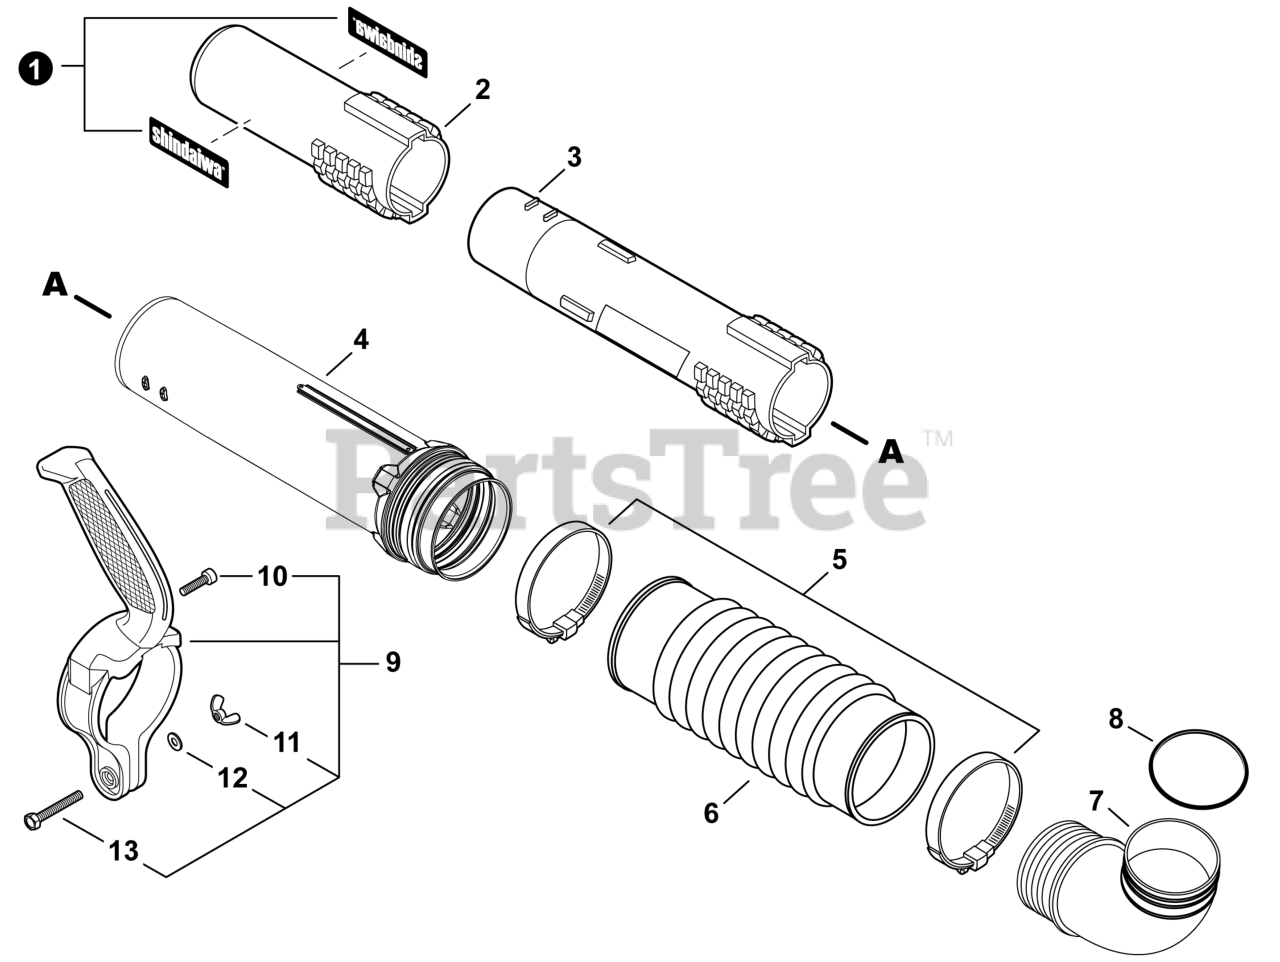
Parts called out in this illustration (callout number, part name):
1	LABEL - SHINDAIWA BLOWER TUBE
2	TUBE, BLOWER - NOZZLE
3	TUBE, BLOWER - STRAIGHT
4	TUBE, BLOWER - SWIVEL
5	CLAMP - BAND 78 MM / 103 MM
6	TUBE, BLOWER - FLEXIBLE
7	TUBE, BLOWER - ELBOW
9	HANDLE KIT - BLOWER TUBE
10	BOLT, TORX 4x16
11	NUT, WING 6
12	WASHER 6.5x11.5x0.8
13	BOLT 6x25
